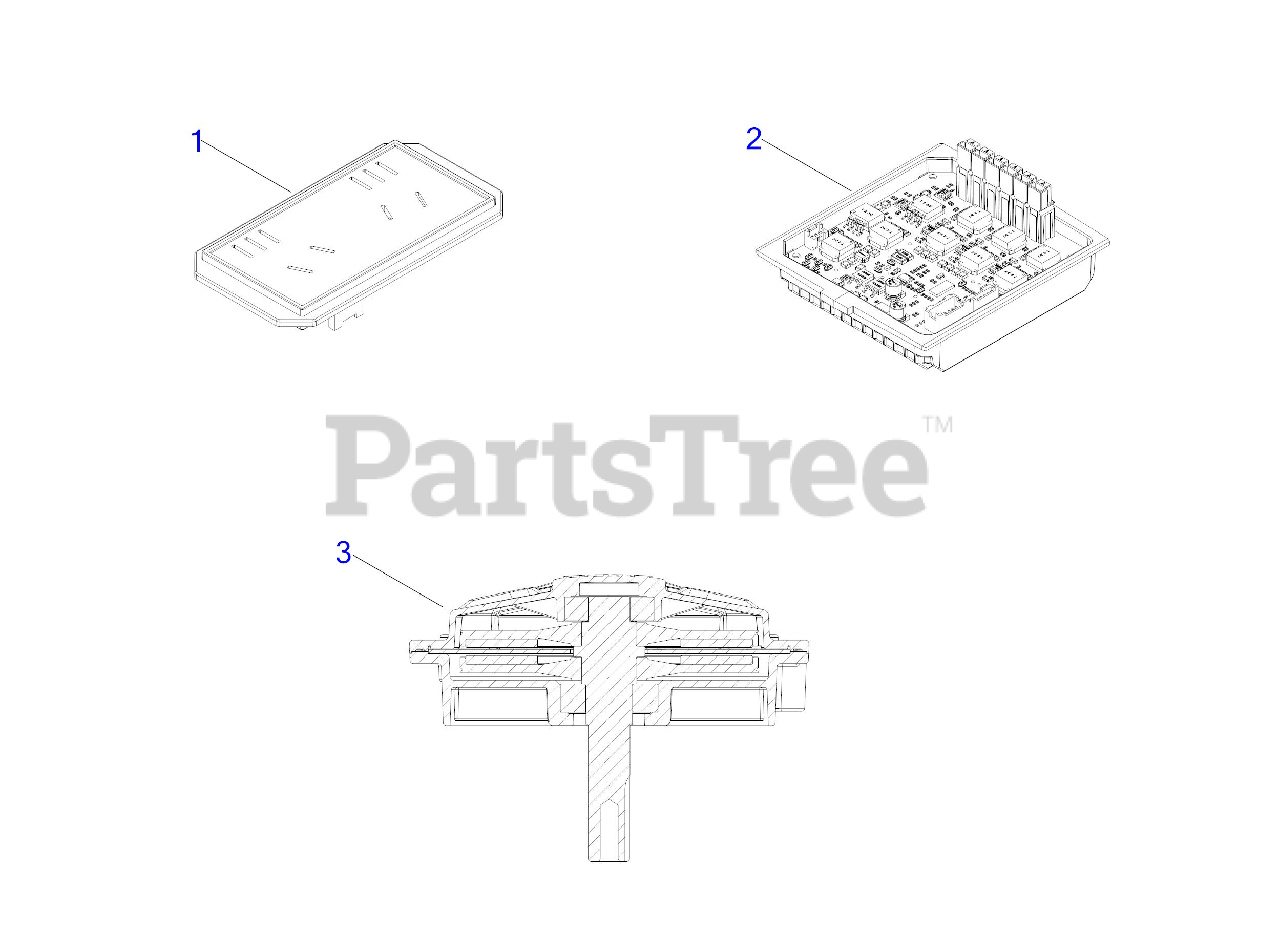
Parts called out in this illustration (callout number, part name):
1	OPERATORS PANEL ASSEMBLY
2	CONTROLLER ASSEMBLY
3	MOTOR ASSEMBLY
